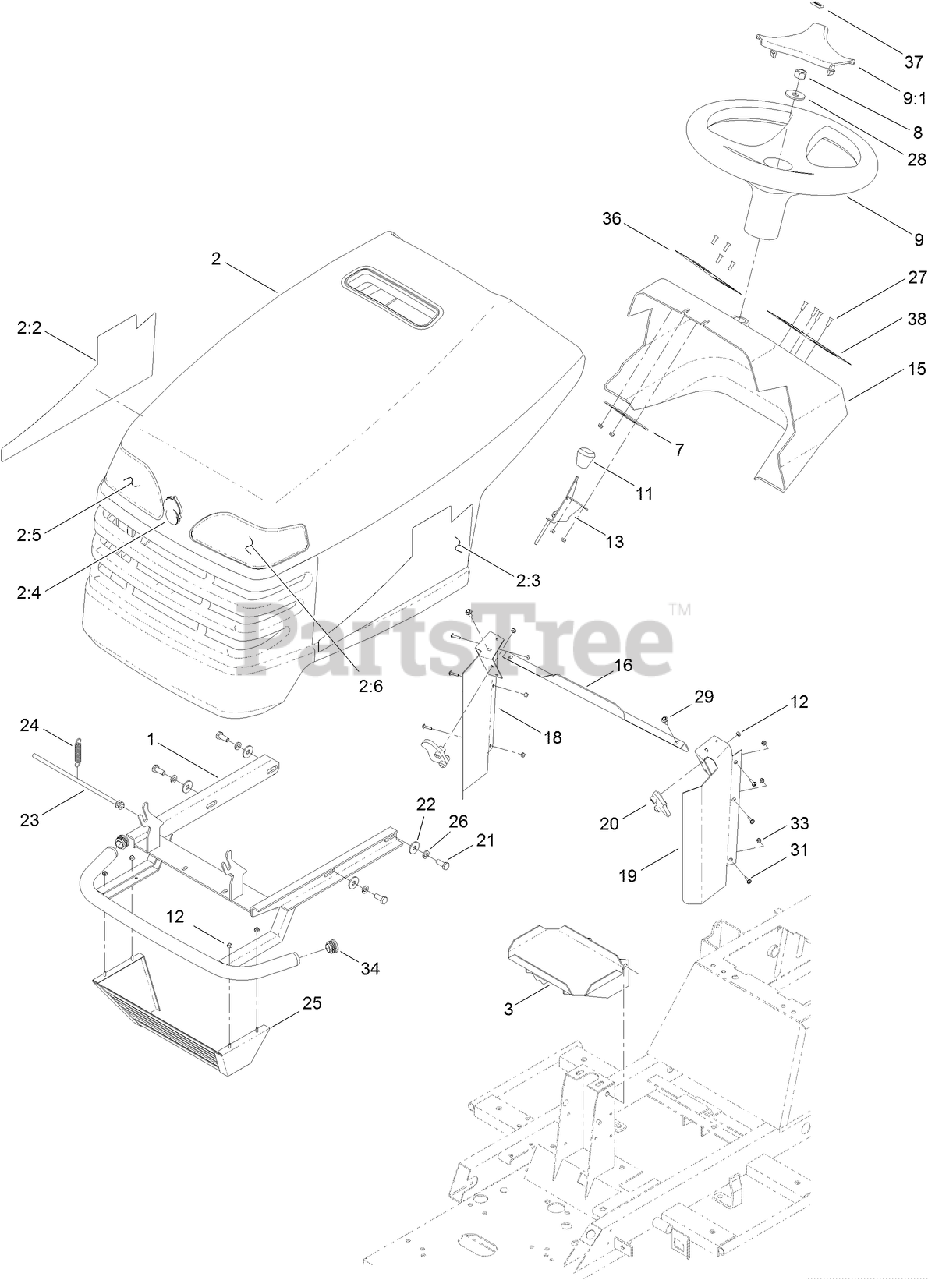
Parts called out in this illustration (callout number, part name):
1	SUPPORT-BUMPER
2	HOOD ASM
2:2	DECAL-HOOD, RH
2:3	DECAL-HOOD, LH
2:4	EMBLEM
2:5	LENS-HEADLAMP, RH
2:6	LENS-HEADLAMP, LH
3	TRAY-BATTERY
8	NUT-HEX
9	WHEEL-STEERING
9:1	COVER-WHEEL, STEERING
12	NUT-LOCK
13	CABLE-THROTTLE AND CHOKE
15	PANEL-DASH
18	PANEL-RIGHT
19	PANEL-LEFT
20	LATCH-HOOD
21	SCREW-HH
22	WASHER-PLAIN
24	SPRING-HOOD
25	GUARD-MUFFLER
26	WASHER-LOCK
28	Washer
33	NUT-HEX
34	PLUG-END, TUBE
36	DECAL-CHOKE/THROTTLE/KEY
37	DECAL
38	DECAL-PTO
